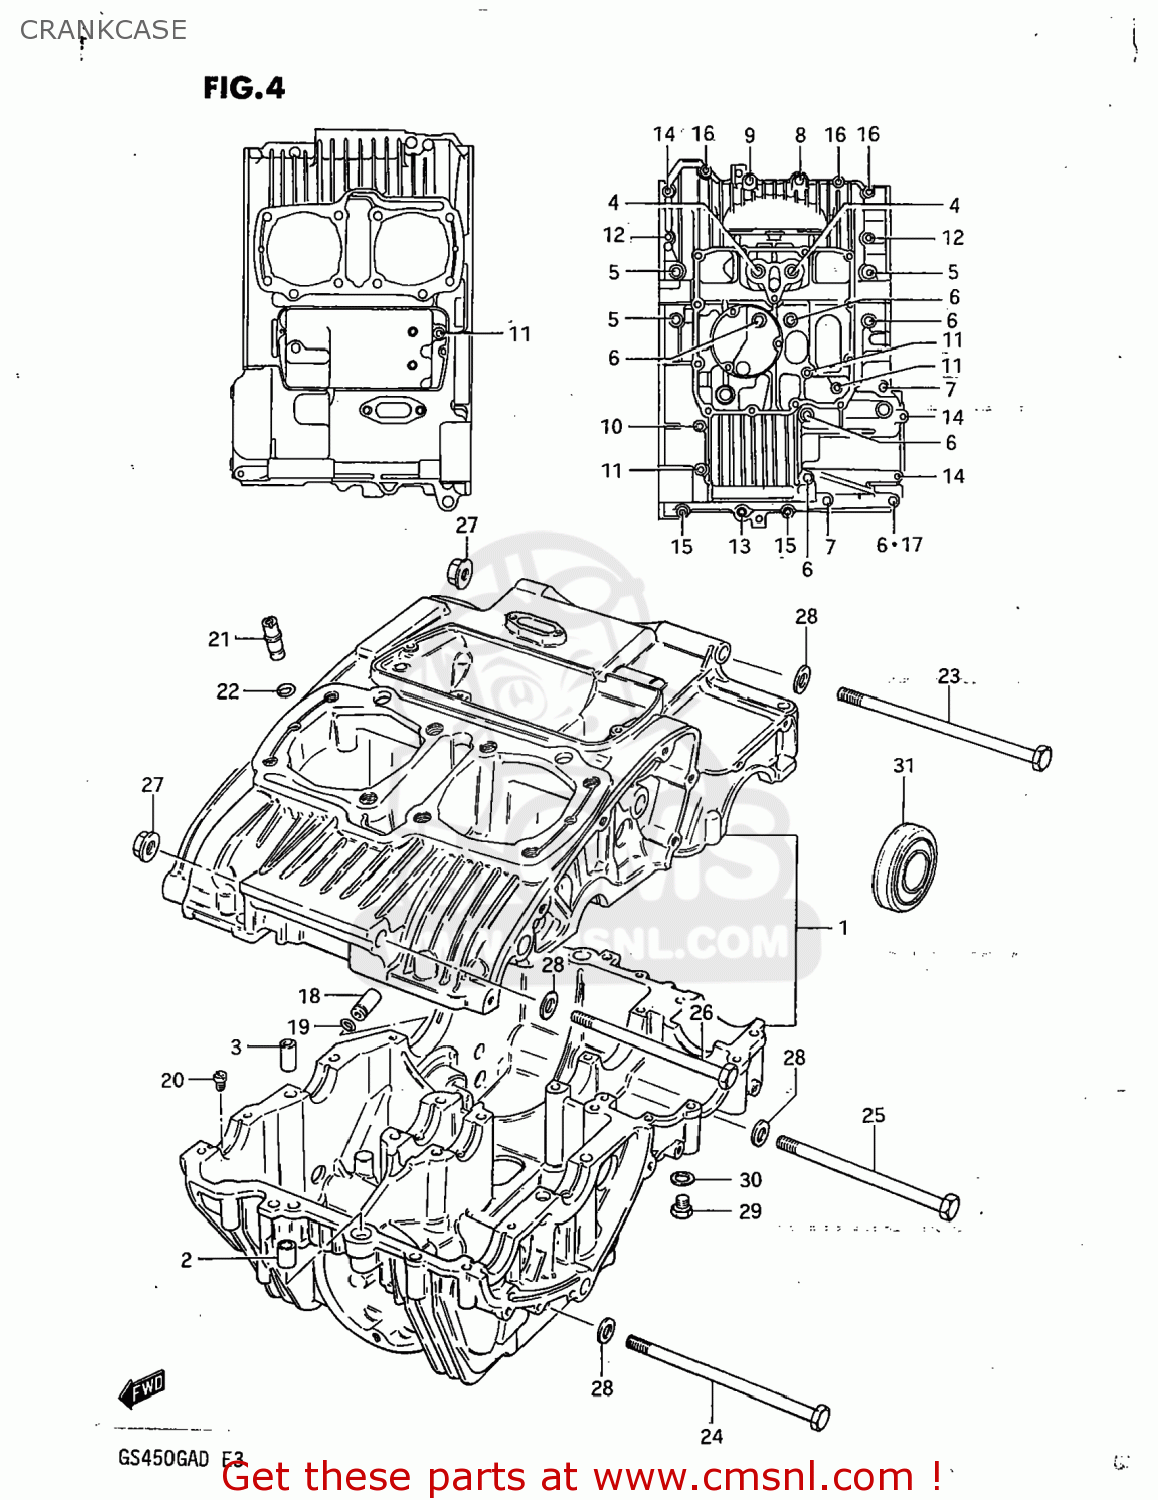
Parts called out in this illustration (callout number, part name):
1	CRANKCASE SET
2	PIN(10.4X13X22)
3	PIN (11X20)(SUS)
4	BOLT
5	BOLT
6	BOLT
7	BOLT (8X70)
8	BOLT 8X65
9	BOLT (8X45)
10	BOLT(6X125)
11	BOLT
12	BOLT (6X90)
13	BOLT (6X70)
14	BOLT 6X65
15	BOLT ,6X50
16	BOLT,UNDER
17	NUT
18	VALVE,CHECK
19	O-RING
20	JET,AIR
21	JET(12)
22	O-RING,OIL GALLERY JET
23	BOLT
24	BOLT(10X210)
25	BOLT 10X160
26	BOLT
27	NUT 10MM
28	WASHER
29	PLUG
30	GASKET(14X19.2X2) (NAS)
31	PLUG
